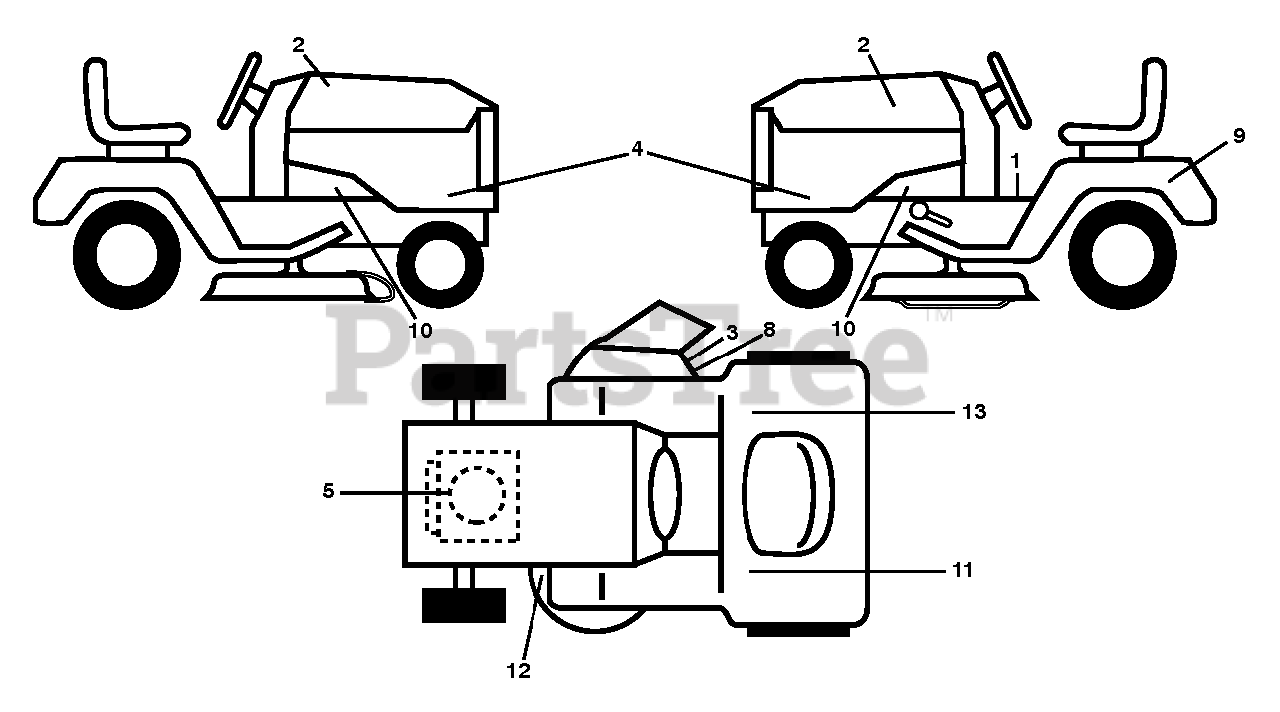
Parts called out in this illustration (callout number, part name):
1	LABEL
2	RP.DECAL.BADGE.170MM.TEXTLOGO
3	DECAL.INTERNATIONL.CUTFINGER
5	DECAL
8	DECAL, DEFLECT WARNING
9	DECAL BTRY SYMBOLS
11	DECAL
12	DECAL V BELT SCHEMATIC
13	DECAL PARK BRAKE
